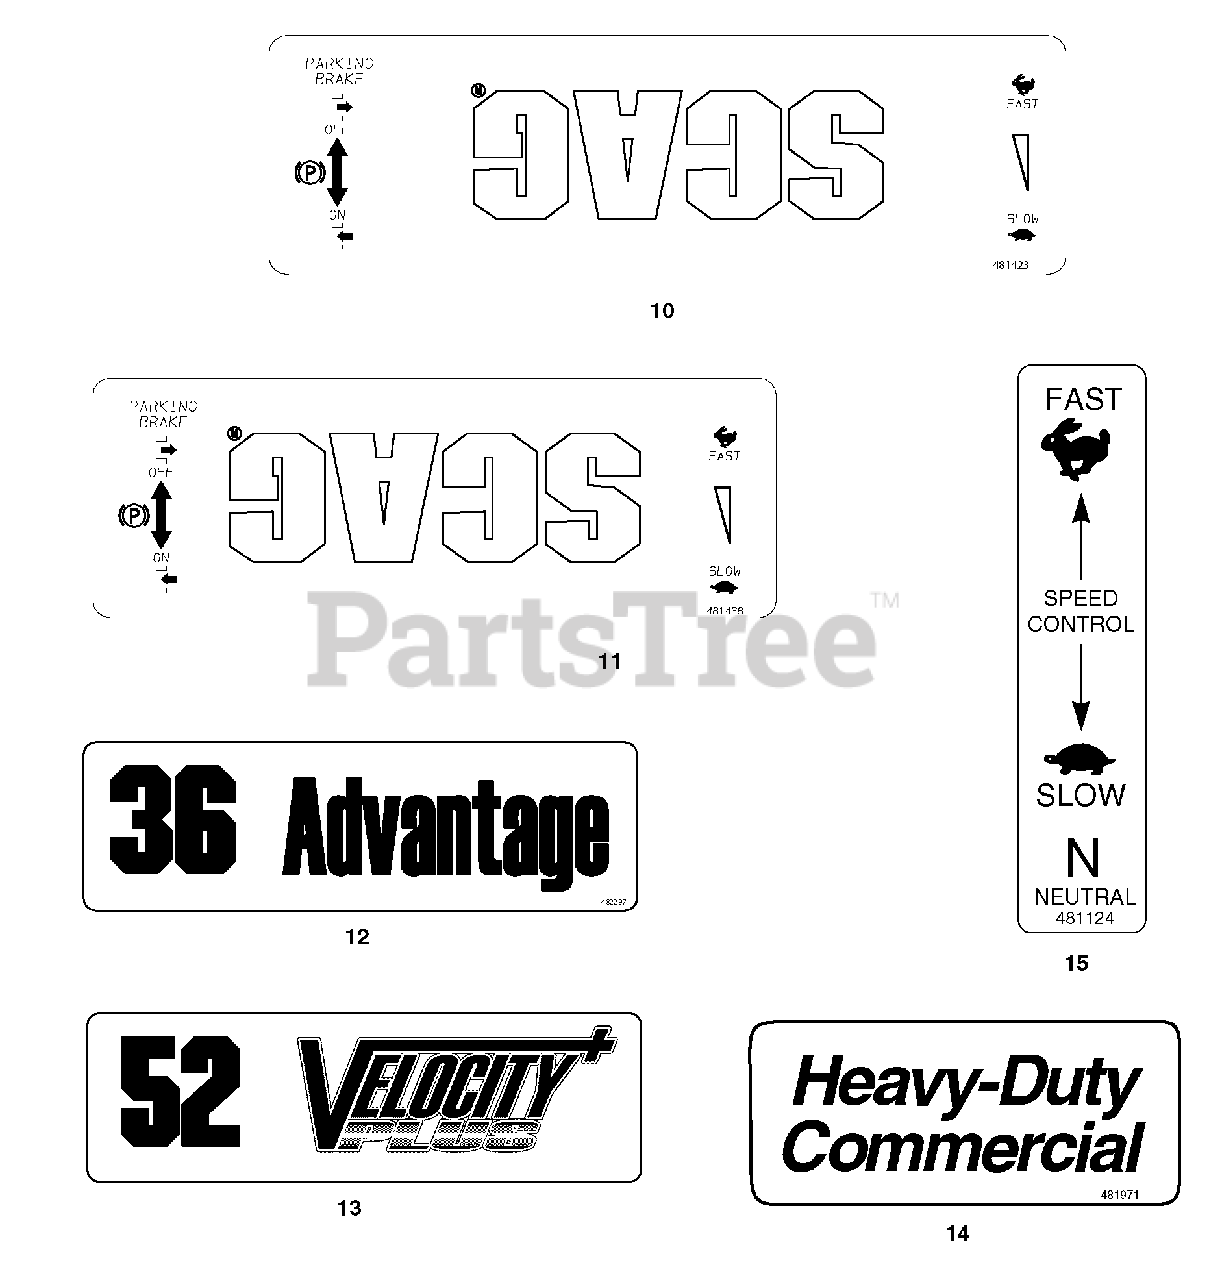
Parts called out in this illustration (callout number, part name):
10	Decal, Instrument Panel - Front
11	Decal, Instrument Panel - Front
12	Decal, 36 Advantage
13	Decal, 48 Velocity Plus
13	Decal, 52 Velocity Plus
13	Decal, 61 Velocity Plis
14	Decal, Heavy Duty Commercial
15	Decal, Speed Control
